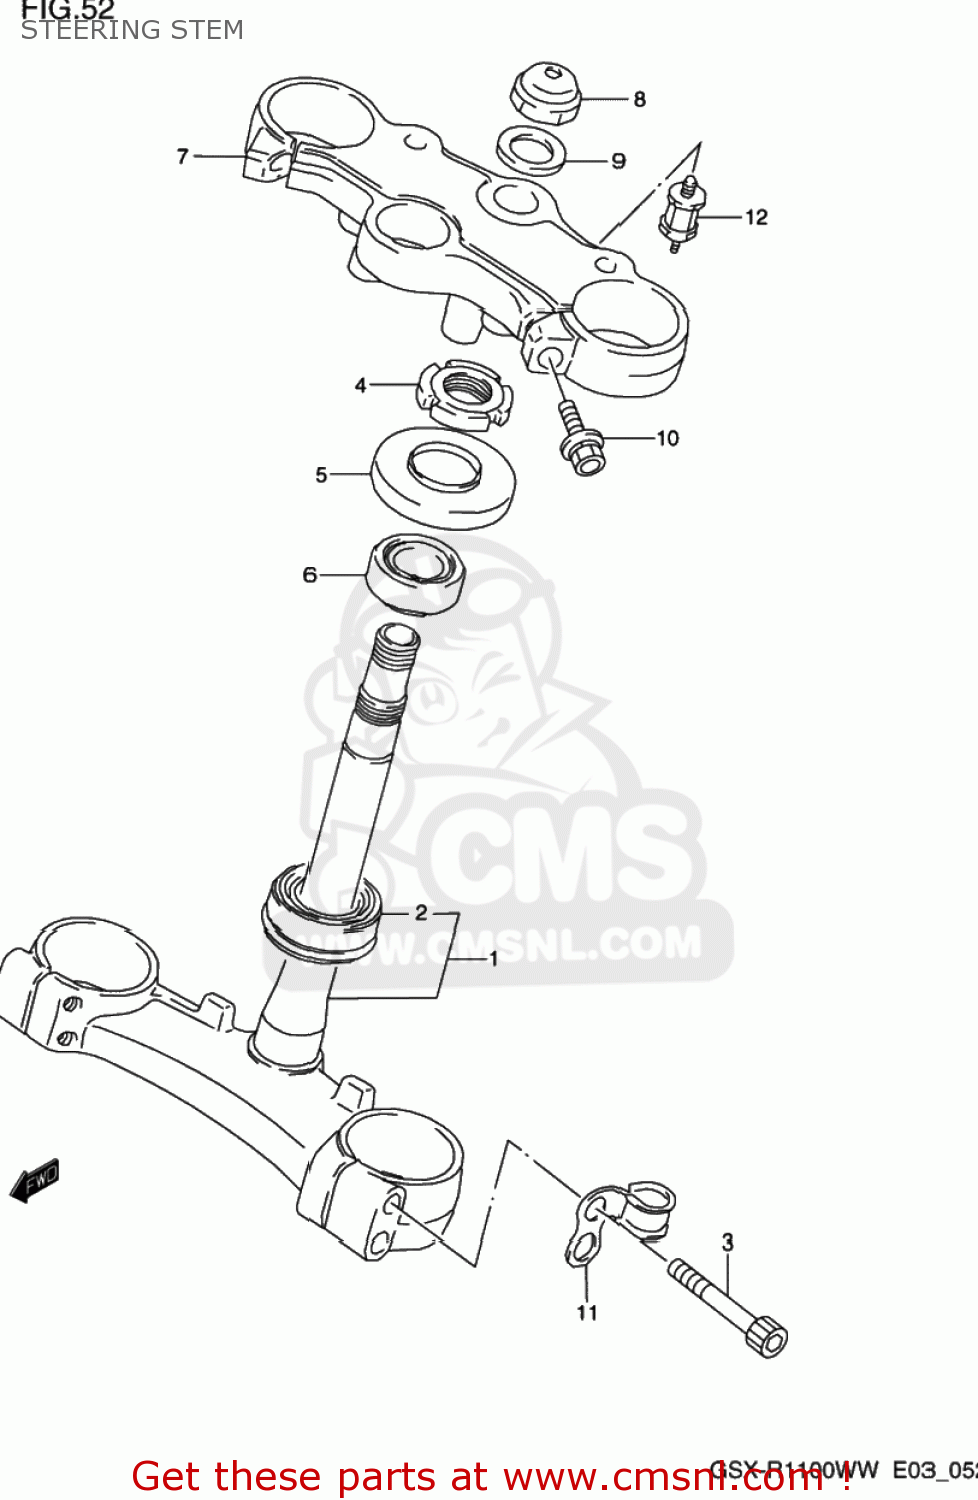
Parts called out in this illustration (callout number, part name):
1	STEM,STEERING
2	BEARING(30X55X17)
3	BOLT
4	NUT,STEERING STEM(25X44X10)
5	SEAL,OIL(34X69X11.9)
6	BEARING(25X47X15)
7	HEAD,STEERING STEM
8	NUT
9	WASHER(22.5X32X1.6)
10	BOLT
11	GUIDE,SPEEDOMETER CABLE
12	BOLT,SPEEDOMETER CUSHION
